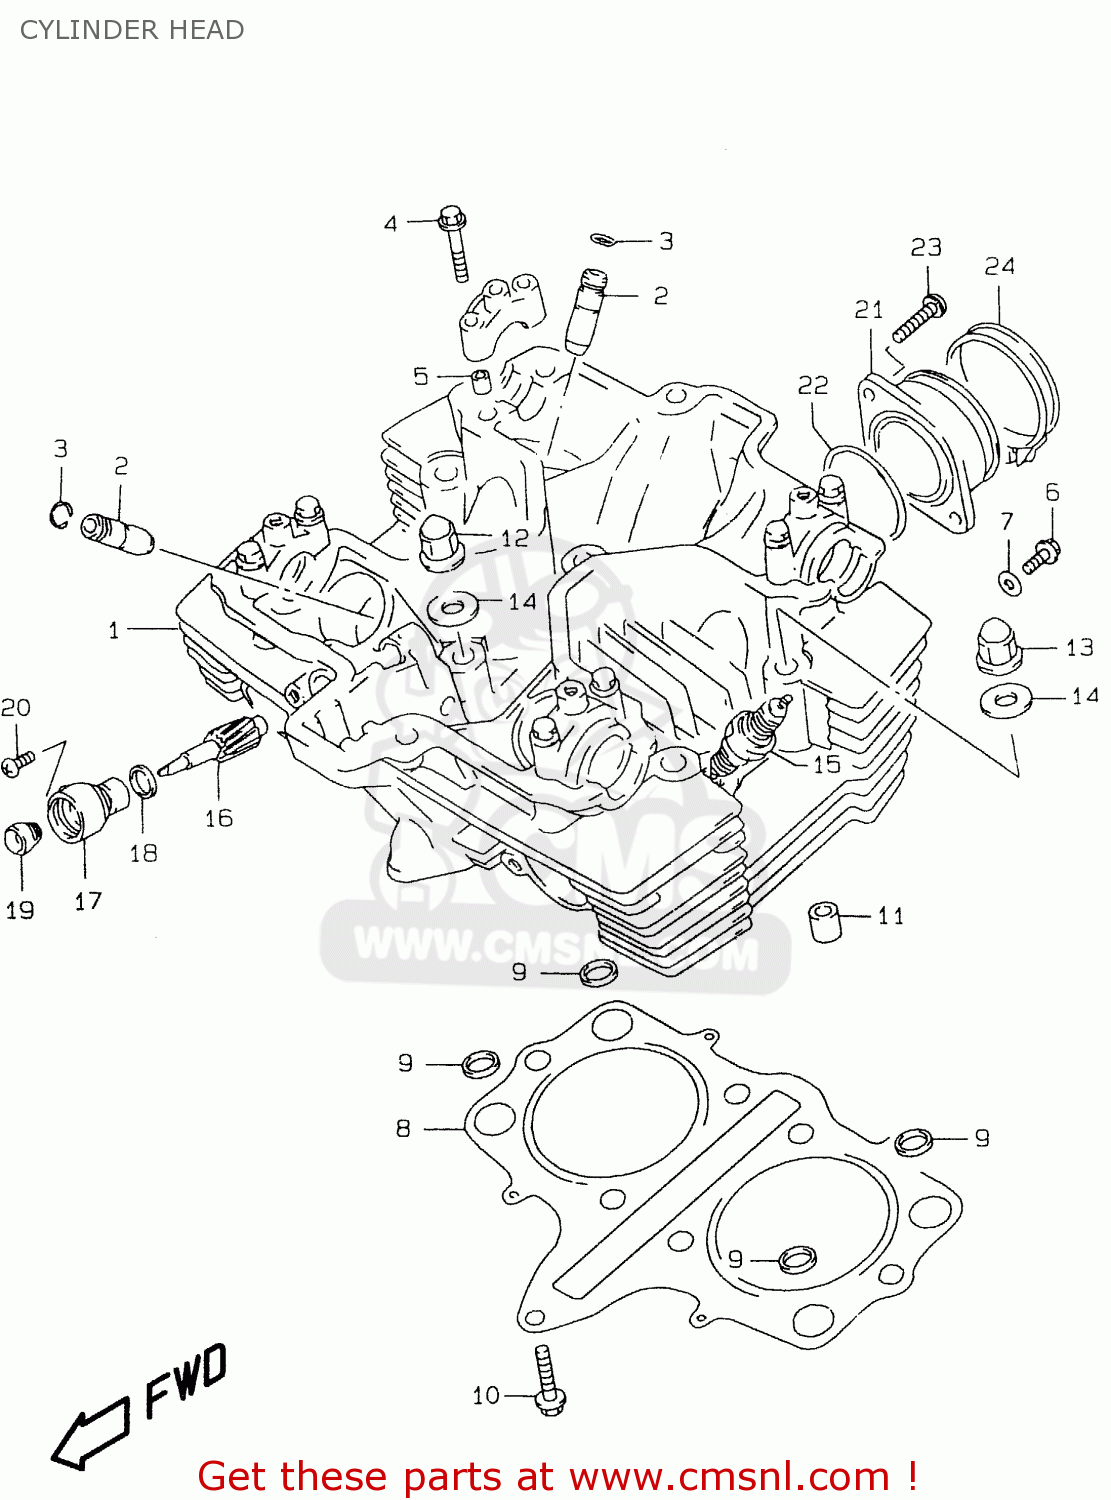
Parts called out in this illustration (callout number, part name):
1	HEAD ASSY,CYLINDER
2	GUIDE,INTAKE VALVE
3	RING,SNAP
4	BOLT(6X39)
5	PIN(6.2X8X11)
6	BOLT
7	GASKET(5.8X13X1.2) (NAS)
8	GASKET,CYLINDER HEAD (NAS)
9	O RING,HEAD GASKET
10	BOLT
11	PIN
12	NUT
13	NUT
14	GASKET(10.2X20X2).3 (NAS)
15	PLUG,SPARK(DPR8EA-9)
16	GEAR,TACHOMETER DRIVEN
17	SLEEVE,TACHOMETER DRIVE GEAR
18	SEAL,TACHOMETER DRIVEN
19	SEAL,OIL(5X12X8)
20	SCREW(5X12)
21	PIPE,INTAKE
22	O RING(D:2.4,ID:39.7)
23	SCREW
24	CLAMP
